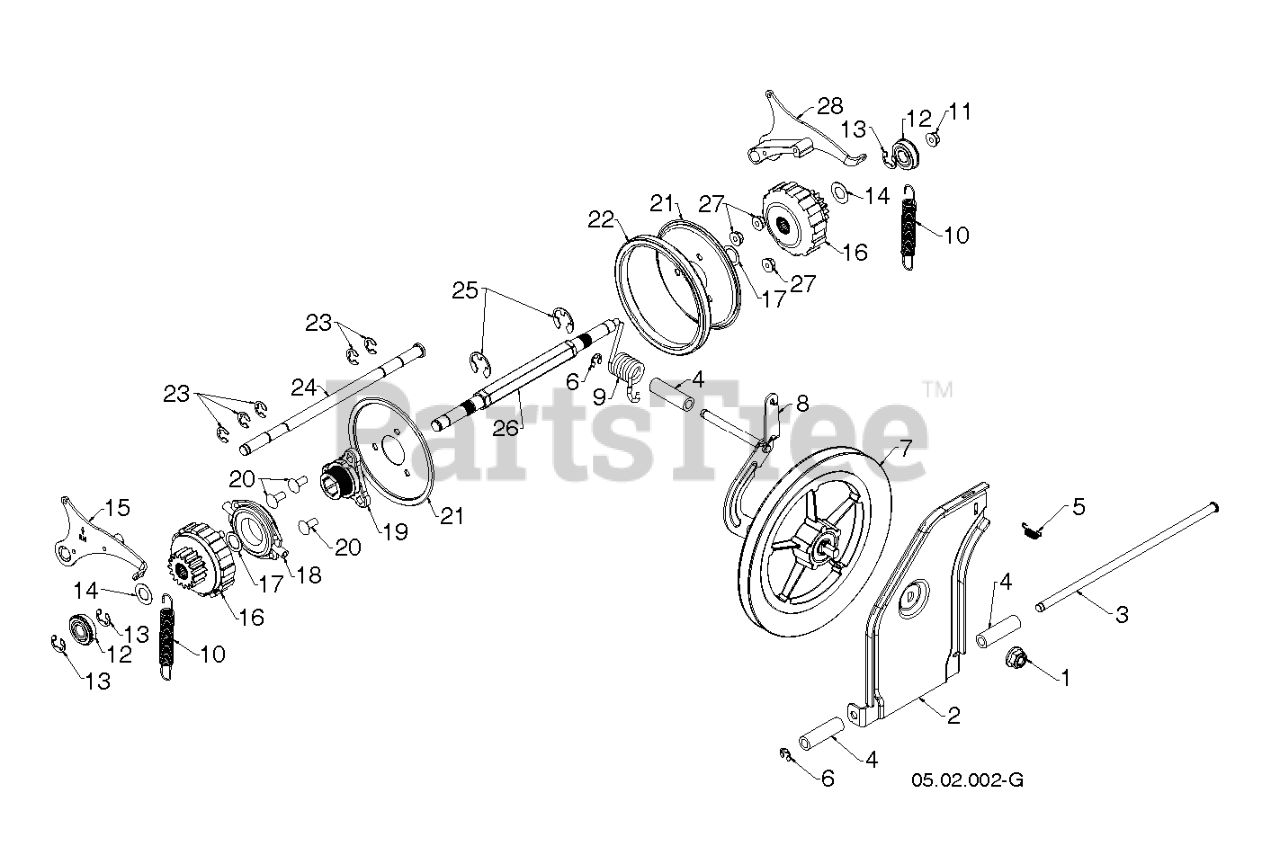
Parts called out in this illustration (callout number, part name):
1	NUT, 1/2-13 HEX FLG NYLOC ZD
2	PLATE.SWING.FRICTION PULLEY.47
3	ROD.TIP.PLATE
4	SPACER YOKE, TORSION SPRING
5	SPRING LATCH
6	E-RING LT
7	PULLEY.FRICTION.DISC.COMBO
8	BRACKET.YOKE.ASSEMBLY.479
9	SPRING TORSION DRIVE
10	SPRING EXTENSION PS
11	NUT.HEX.FLANGE.LOCK.5/16-18
12	BEARING 9/16 ID. SNR
13	RING.RETAINING.1622-2RSNR.CLER
14	WASHER FLAT.637IDX1.00ODX21GA
15	PAWL.ASM.RH.SNOW
16	GEAR.ASM.PLANETARY
17	WASHER FLAT.59IDX1.065ODX25GA
18	TRUNNION BEARING ASSY
19	HUB.RUBBER.WHEEL
20	BOLT.CARR.SQNK.5/16-18UNC.X3/4
21	PLATE.RUBBER.WHEEL.BLACK
22	RING RUBBER
23	CLIP E-RING_.500 SHAFT
24	ROD ROD, PAWL ROD
26	SHAFT SHAFT, PWR STR SHAFT
27	NUT.LOCK.5/16-18
28	PAWL.ASM.LH.SNOW
